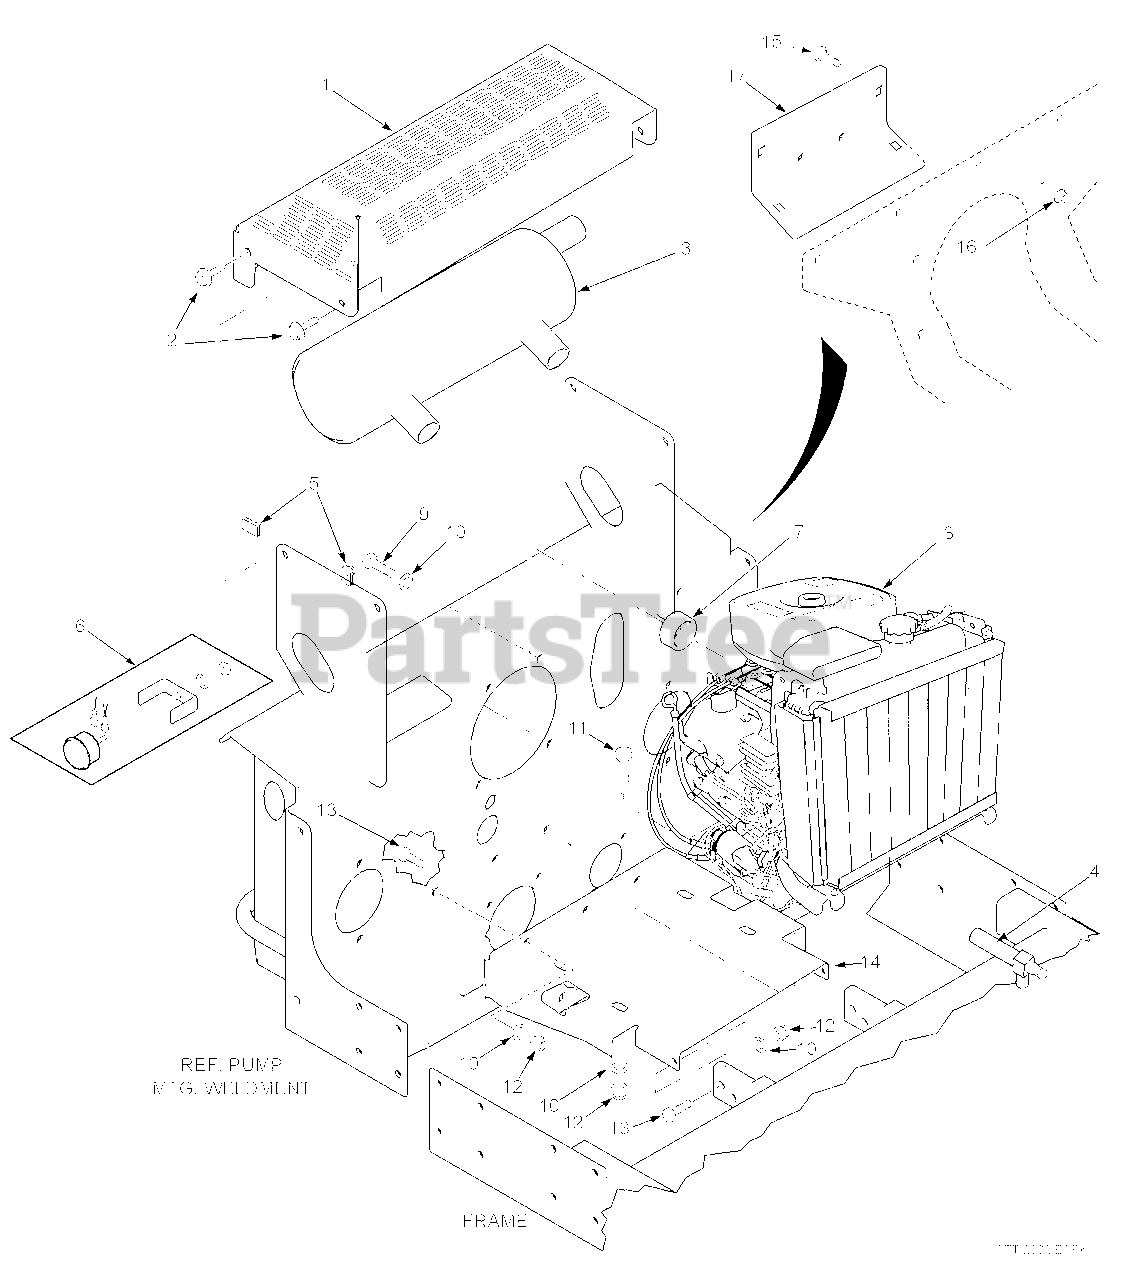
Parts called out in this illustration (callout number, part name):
1	Muffler Guard
2	Screw, Hex Serrated Flange 1/4-20 x 3/4"
3	Muffler
4	Extension, Oil Drain
5	U-Nut, 1/4-20
6	Hour Meter
7	Spacer, Engine
8	Engine, Kawasaki 27KA
9	Bolt, M10-1.50 x 25 Grade 8.8
10	Lockwasher, 3/8" Spring
11	Bolt, Hex Head 3/8-16 x 1-3/4"
12	Nut, Hex Elastic Stop 3/8-16
13	Bolt, Hex Head 3/8-16 x 1-1/4"
14	Plate, Engine Mounting
15	Bolt, Carriage 5/16-18 x 3/4"
16	Nut, Hex Serrated Flange 5/16-18
17	Rear Cover
18	Screen Weldment, Radiator
